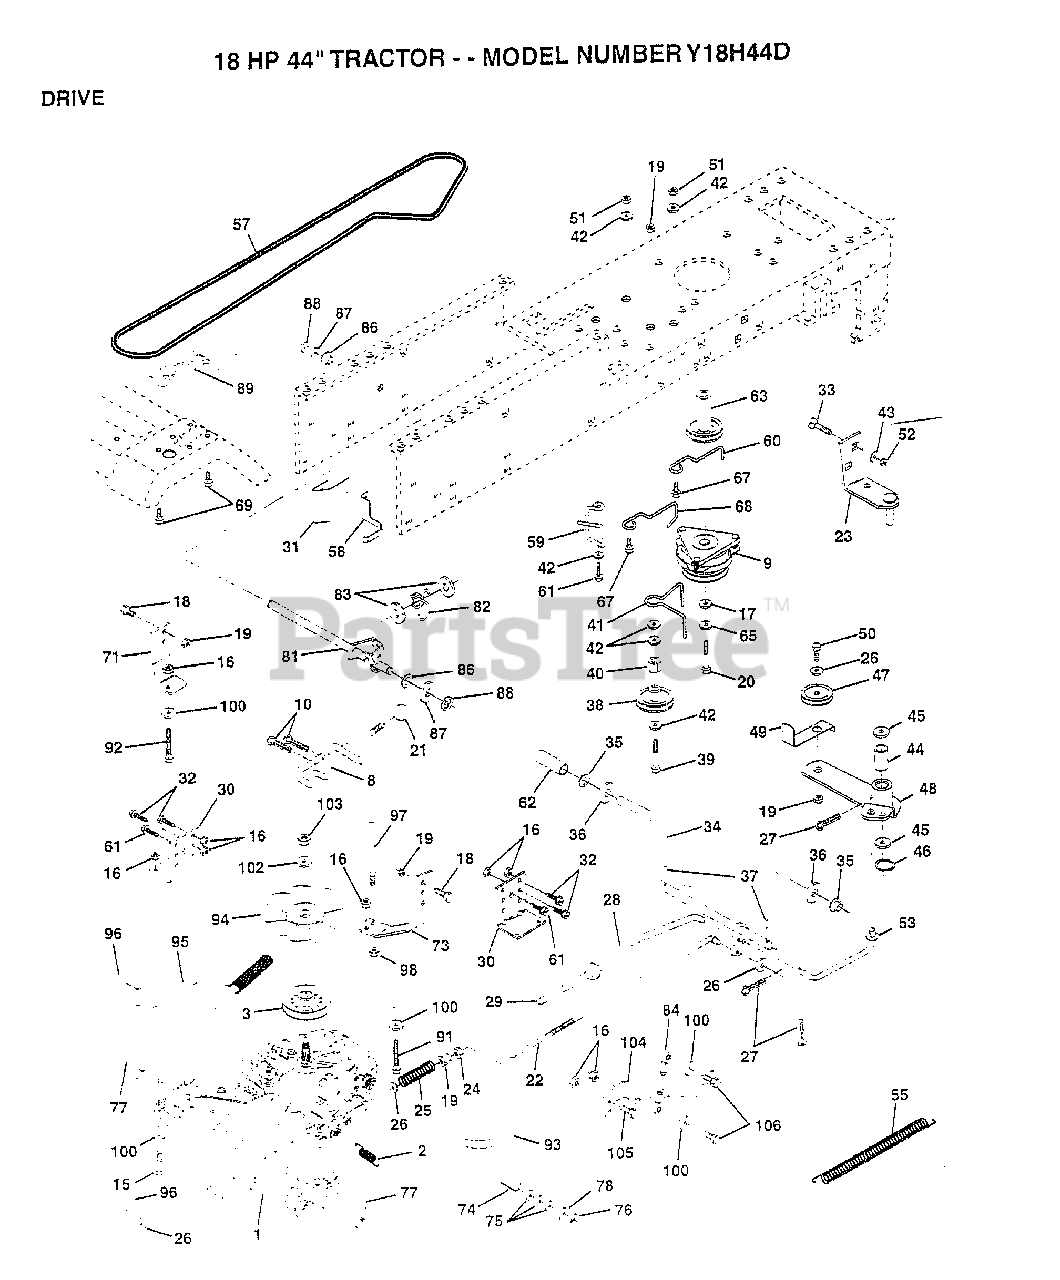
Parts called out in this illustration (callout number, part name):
2	SPRING RET BRAKE
3	PULLEY.TRANSAXLE
10	PIN COTTER 1/8
15	BOLT HEX
16	NUT
17	WASHER
18	BOLT
19	NUT
21	KNOB.DUCKHEAD.1/2
23	BRACKET.ASM.MTG
24	NUT
25	SPRING ROD LT
26	WASHER
27	COTTER PIN
28	BRAKE PARK ROD
29	CAP, PARKING BRAKE
30	TRANSAXLE MTG BKT
31	"KEEPER,BELT LH T"
32	BOLT
33	BOLT
35	NYLON BEARING
36	WASHER LT
38	PULLEY.IDLER.FLAT
39	BOLT
40	SPACER T
41	BELT KEEPER LT
42	WASHER
43	WASHER T
44	"LY, BEARING"
45	WASHER LT
46	KLIP RING
48	ARM IDLER
49	RETAIN BELT
53	"LINK, CLUTCH T"
55	"SPRING, RETURN LT"
57	"BELT.GD DRV 82"""
58	KEEPER BELT LH
59	KEEPER BELT CNTSP
60	KEEPER BELT ENGLH
61	SCREW
62	PEDAL COVER T
63	PULLEY CLU ELEC
65	LOCKWASHER
67	BOLT
68	"KEEPER,BLT ENG LT"
69	SCREW HEXWSH H-L
71	STRAP TORQ LH HYD
73	STRAP TORQ RH HYD
74	SPACER SPLIT
75	WASHER
76	E-RING LT
77	SQUARE KEY
78	WASHER
82	"SPRING,TORSION"
83	WASHER
84	ROD.TIE.BALL.4.75
86	BUSHING
87	WASHER D
88	KLIP RING
92	HEX BOLT
93	"LINE FUEL HYD 4"""
94	"FAN 7"" HYDRO"
96	RETAINER M
97	BOLT KEEPER RH
98	NUT
100	WASHER M
102	WASHER BELLEVILLE
103	NUT NYLON 1/2-20
104	ARM CONTROL HYDRO
105	SCREW CAP 5/16-18
106	BOLT
